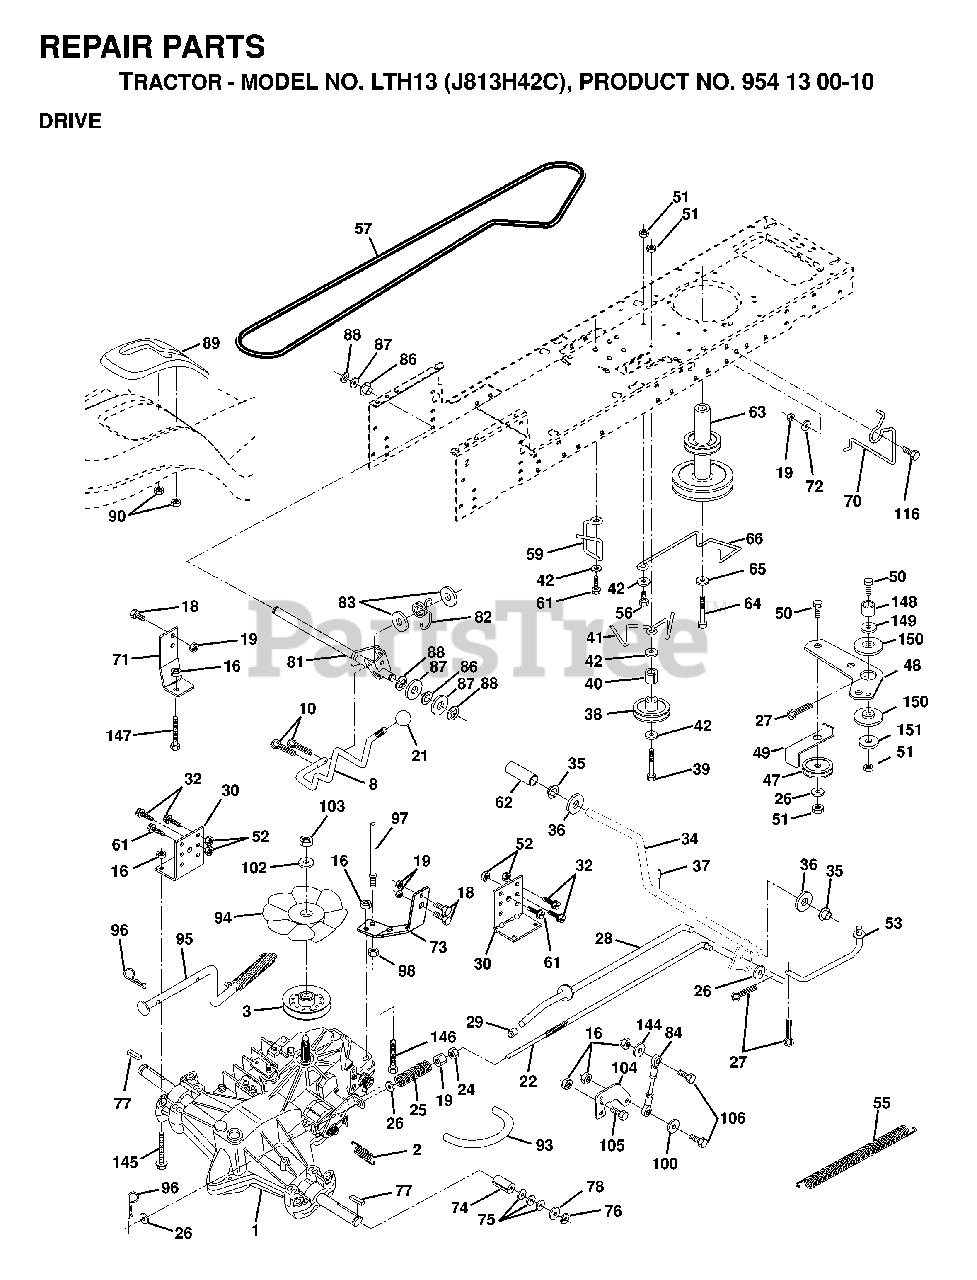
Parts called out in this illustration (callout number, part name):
2	SPRING BRAKE
3	PULLEY, TRANSAXLE
8	ROD SHIFT FENDER
10	PIN COTTER
16	NUT.71038.31-18.HEX.NYLOCK
19	NUT
21	PISTOL KNOB
22	ROD BRAKE HYDRO
24	NUT
25	SPRING ROD LT
27	COTTER PIN
28	ROD BRAKE PARK LT
29	PLUNGER CAP
30	BRACKET TRANSAXLE
31	KEEPER BELT LH
32	BOLT
34	SHAFT, FOOT PEDAL
35	BEARING.NYLON
36	WASHER LT
37	DRIVE PIN
38	PULLEY.IDLER.FLAT
41	KEEPER, BELT IDLER
42	WASHER
47	IDLER PULLEY
48	BELLCRANK, CLUTCH
49	RETAIN BELT
50	BOLT
51	LOCKNUT
52	LOCKNUT
53	LINK, CLUTCH LT
55	SPRING, RETURN LT
59	KEEPER CENTER SPAN
61	SCREW
62	PEDAL COVER T
63	PULLEY ENGINE
64	BOLT
65	LOCKWASHER
66	KEEPER BELT ENGINE
70	KEEPER BELT ENG
71	STRAP LH TORQUE
73	STRAP TORQUE RH HYDRO
74	SPACER SPLIT
76	E-RING LT
77	SQUARE KEY
81	SHAFT ASSY
82	SPRING,TORSION
83	WASHER
86	BUSHING.STEERING.ROD
88	KLIP RING
89	SHIFT CONSOLE
93	FUEL LINE
94	FAN 7" HYDRO
95	CONTROL ARM, BYPASS HYDRO
96	RETAINER M
97	KEEPER BELT RH
100	WASHER M
103	NUT.HEX.1/2-20
104	CONTROL ARM
106	BOLT.5/16-18X1-1/4 FULL.THREAD
116	BOLT
144	WASHER
146	BOLT
148	GUIDE
149	SPACER RETAINER
150	BUSHING NYLON COLLERED
151	WASHER 12/32X2X10GA
